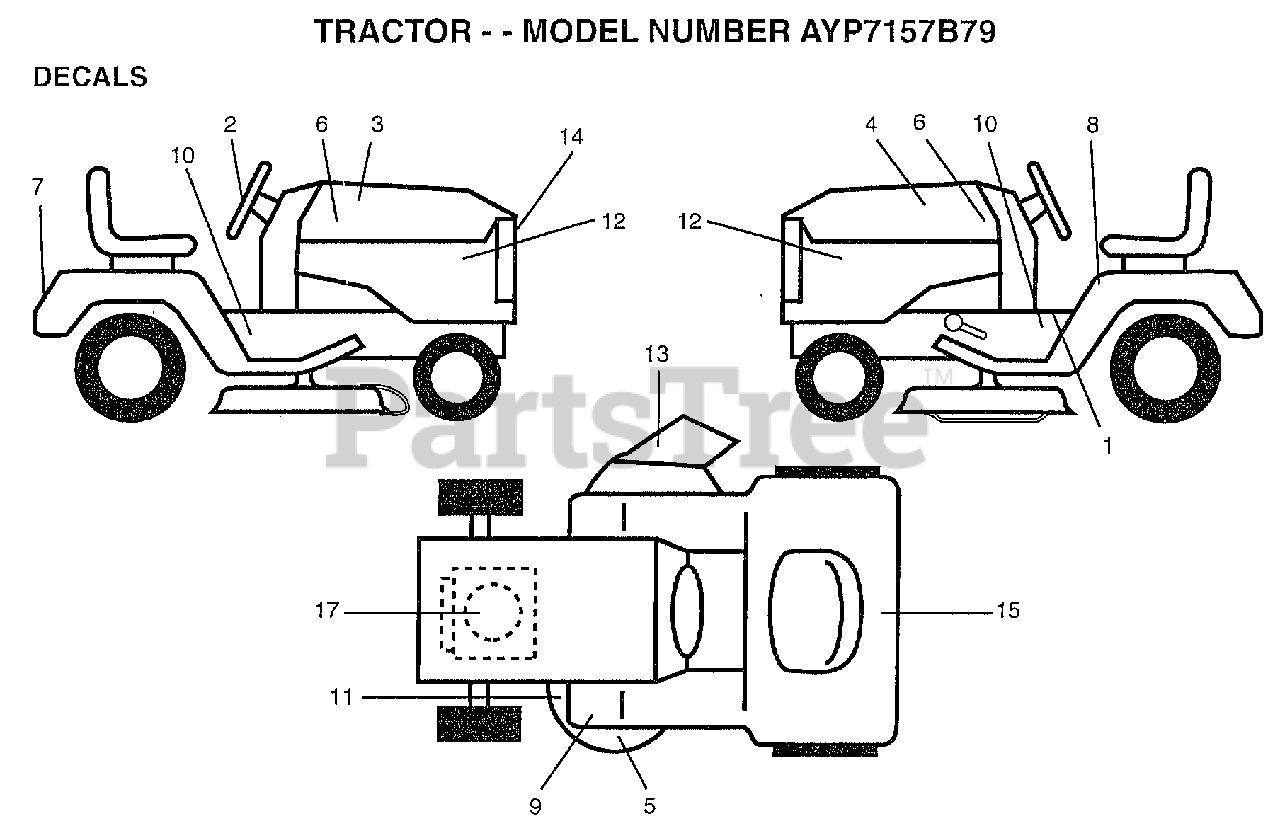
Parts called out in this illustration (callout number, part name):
1	"DECAL DASH,OPER."
2	DECAL STEER WHL
3	DECAL HOOD RH
4	DECAL HOOD LH
5	DECAL DECK WIZ +
6	NAMEPLATE.HD.WIZA
8	"DECAL DANGER,FEND"
10	DECAL CHASSIS WIZ
11	DECAL
12	"DECAL PANEL,SIDE"
13	DECAL DECK MULCH
14	DECAL.LENS.WIZARD
15	DECAL.BATRY.3-3908
17	DECAL, ENGINE
